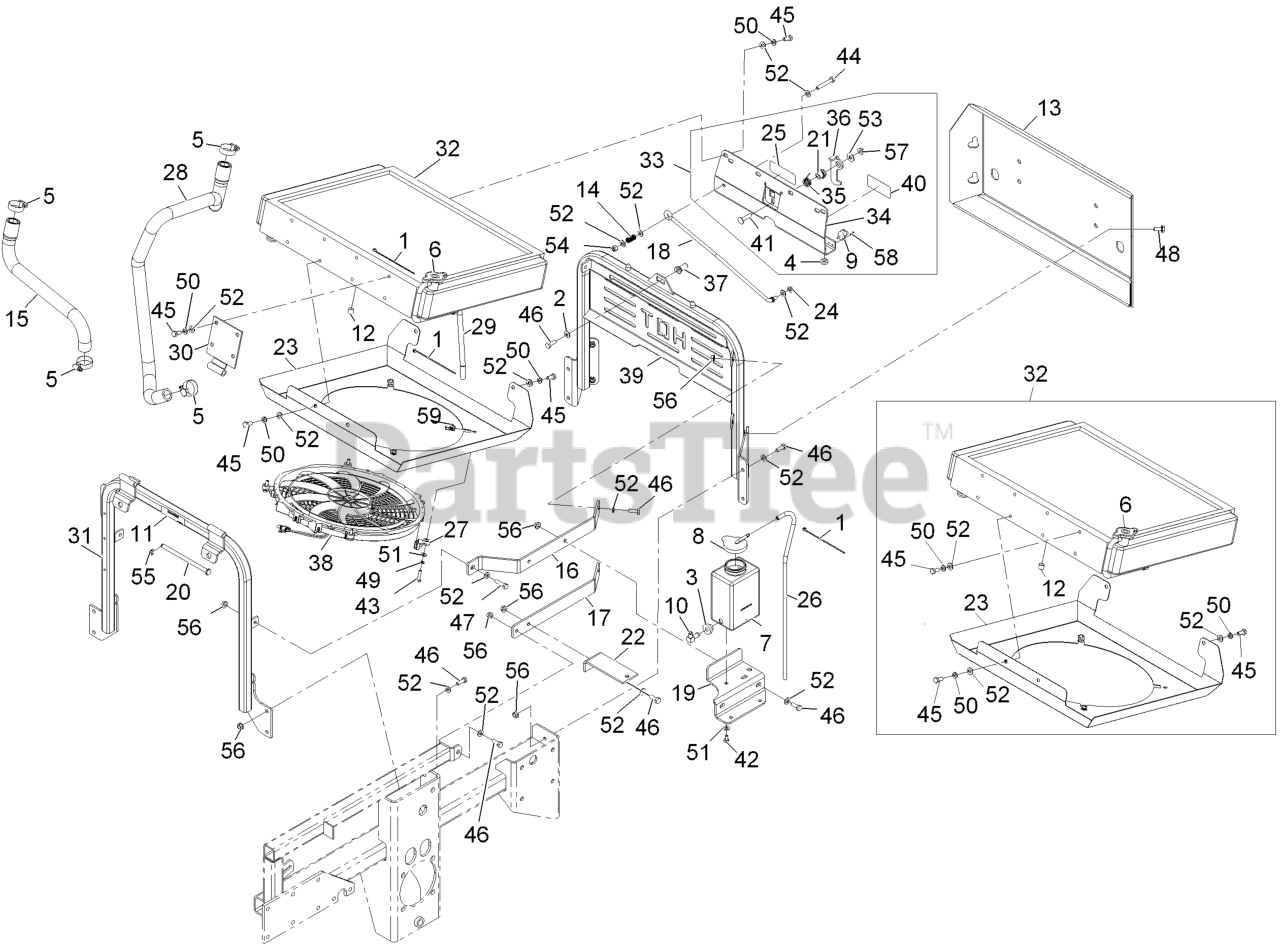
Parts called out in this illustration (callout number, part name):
1	TIE-CABLE
2	WASHER-SPRING
6	CAP-RADIATOR
7	TANK-OVERFLOW
8	CAP-TANK, OVERFLOW
11	DECAL-COVER, MISSING
12	PLUG-PIPE
13	WLD,REAR BUMPER
14	SPRING,LOCK PIN
15	HOSE,RADIATOR UPPER D902(
17	RIB, BOTTOM
18	ROD,PROP
19	BRACKET,BOTTLE
21	BUSHING-LATCH, SEAT
22	BRACKET, HYDRAULIC TANK
23	SHROUD,FAN
25	DECAL,RADIATOR ASSEMBLY
27	MOUNT,FAN
28	HOSE,RADIATOR LOWER D902
29	HOSE,OVERFLOW
30	WLD,HINGE PLATE
31	ASM, RAD. MOUNT W/ DECALS
33	ASM-LATCH PLATE
34	ASM,LATCH PLATE S.O.
35	SPRING,LATCH
36	HOOK,LATCH
37	PIN,LATCH
39	WLD,REAR GUARD
40	DECAL-ANTIFREEZE
41	SCREW-CARR
42	SCREW-HH
43	SCREW-HH
44	SCREW-HH
45	SCREW-HH
46	SCREW-HH
47	SCREW-HH
48	SCREW-HHF
49	SCREW-HH
50	WASHER-LOCK
51	WASHER-FLAT
52	WASHER-PLAIN
53	WASHER-FLAT
54	NUT-LOCK, NI
59	Nut-Retainer-Panel 1/4-20
